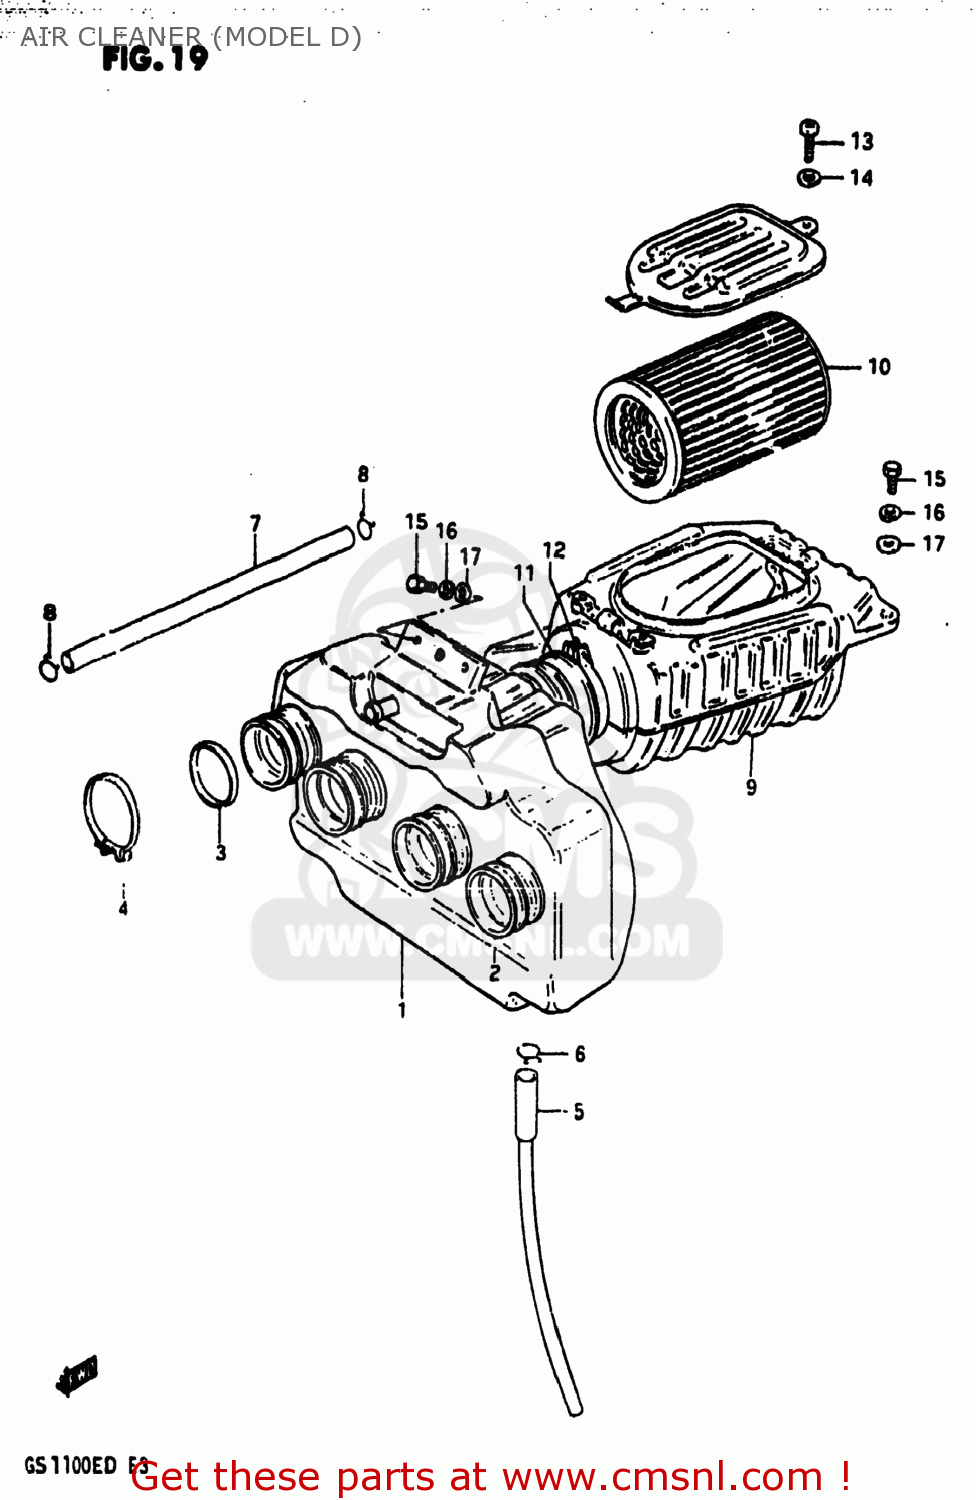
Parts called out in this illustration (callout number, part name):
1	CASE,AIR CHAMBER
2	TUBE,AIR CLEANER OUTLET
3	RING,CARBURETOR AIR INLET HOSE
4	CLAMP
5	DRAIN TUBE
6	CLIP
7	HOSE
8	CLIP
9	CLEANER SET,RR AIR
10	FILTER ASSY
11	HOSE,AIR CLEANER
12	BAND
13	SCREW
14	WASHER
15	BOLT
16	LOCK WASHER
17	WASHER
